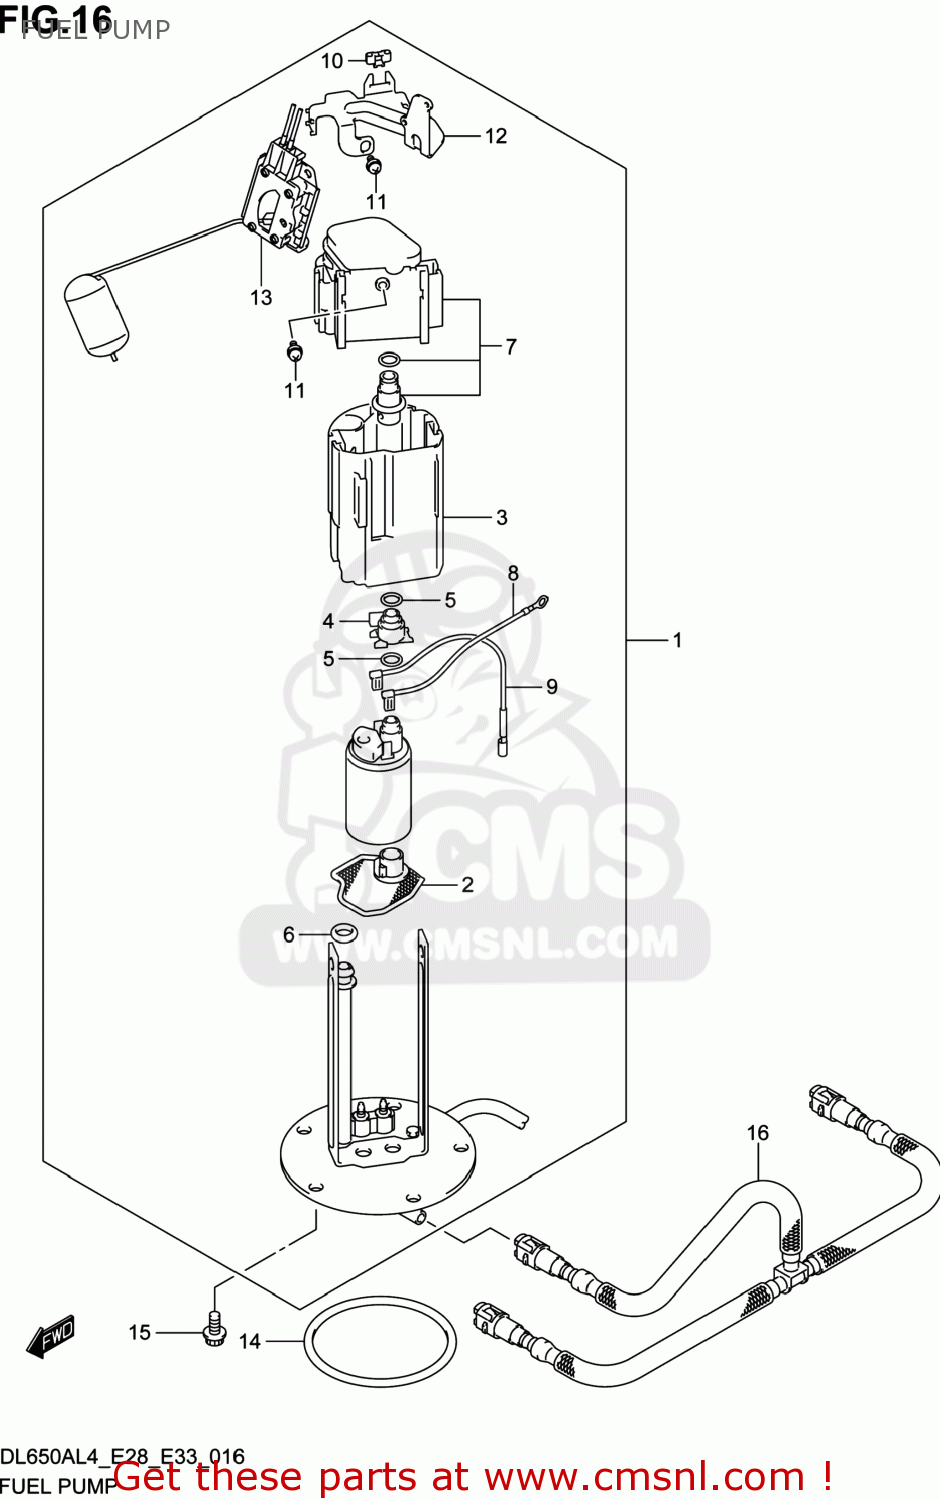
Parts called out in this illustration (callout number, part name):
1	PUMP ASSY,FUEL
2	STRAINER
3	CUP
4	JOINT
5	O RING
6	O RING
7	REGULATOR,FUEL
8	WIRE,EARTH
9	WIRE,LEAD
10	SADDLE,EDGE
11	SCREW
12	BRACKET,FUEL GAUGE
13	GAUGE ASSY,FUEL LEVEL SENDER
14	O RING,FUEL PUMP
15	BOLT
16	HOSE,FUEL
